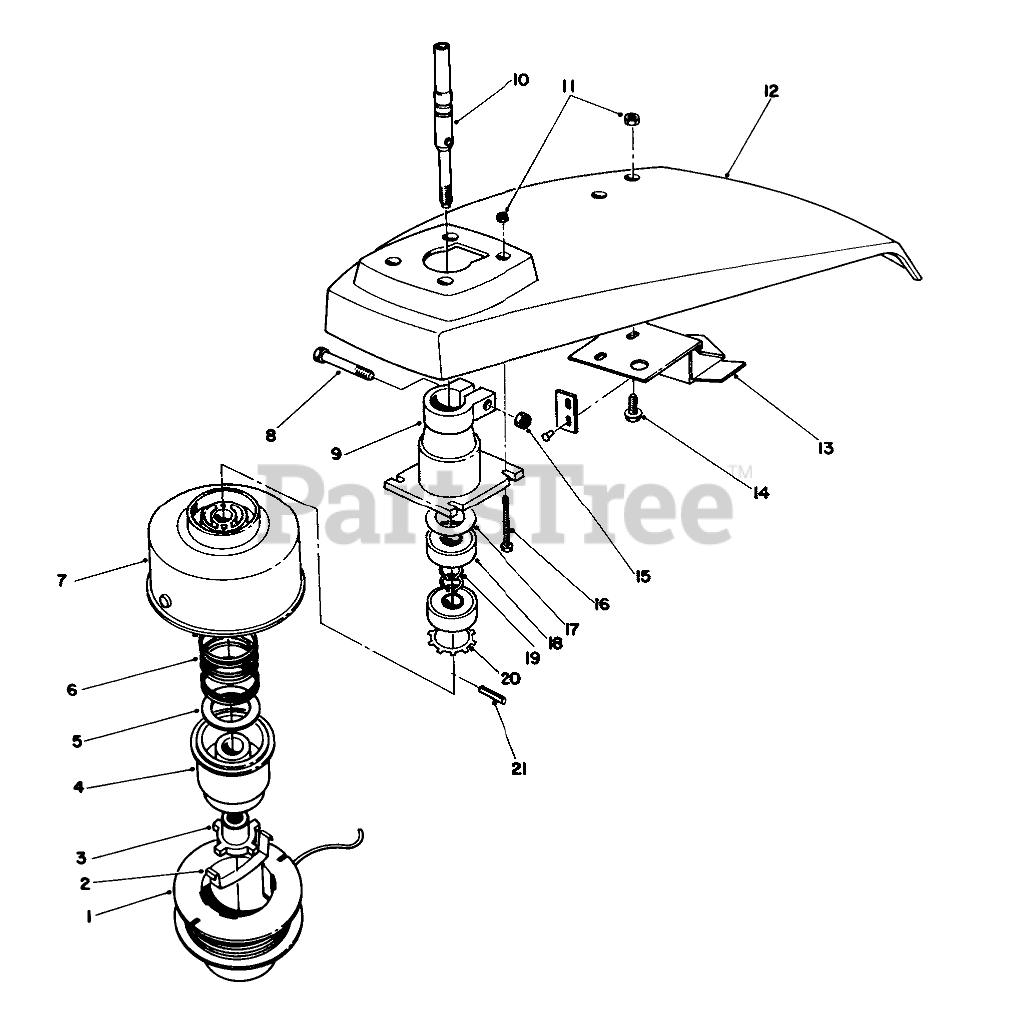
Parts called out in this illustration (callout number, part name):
1	Empty Spool
2	SADDLE-SPOOL CAP
3	DRIVER
4	SPOOL CORE
5	WASHER-FLAT
6	SPRING COMPRESSION
7	DRUM/EYELET
8	SCREW-HH
9	Housing-Bearing (Incl. Ref. #10, 17-21)
10	Shaft-Power
11	NUT-LOCK, NI
12	GRASS SHIELD-PLASTIC
13	BRKT/KNIFE BLD ASM
14	SCREW-HWH
15	NUT-LOCK, NI
16	SCREW-HH
17	Washer
18	Ball Bearing
19	Snap Ring
20	Grip-Spring
21	COIL PIN
